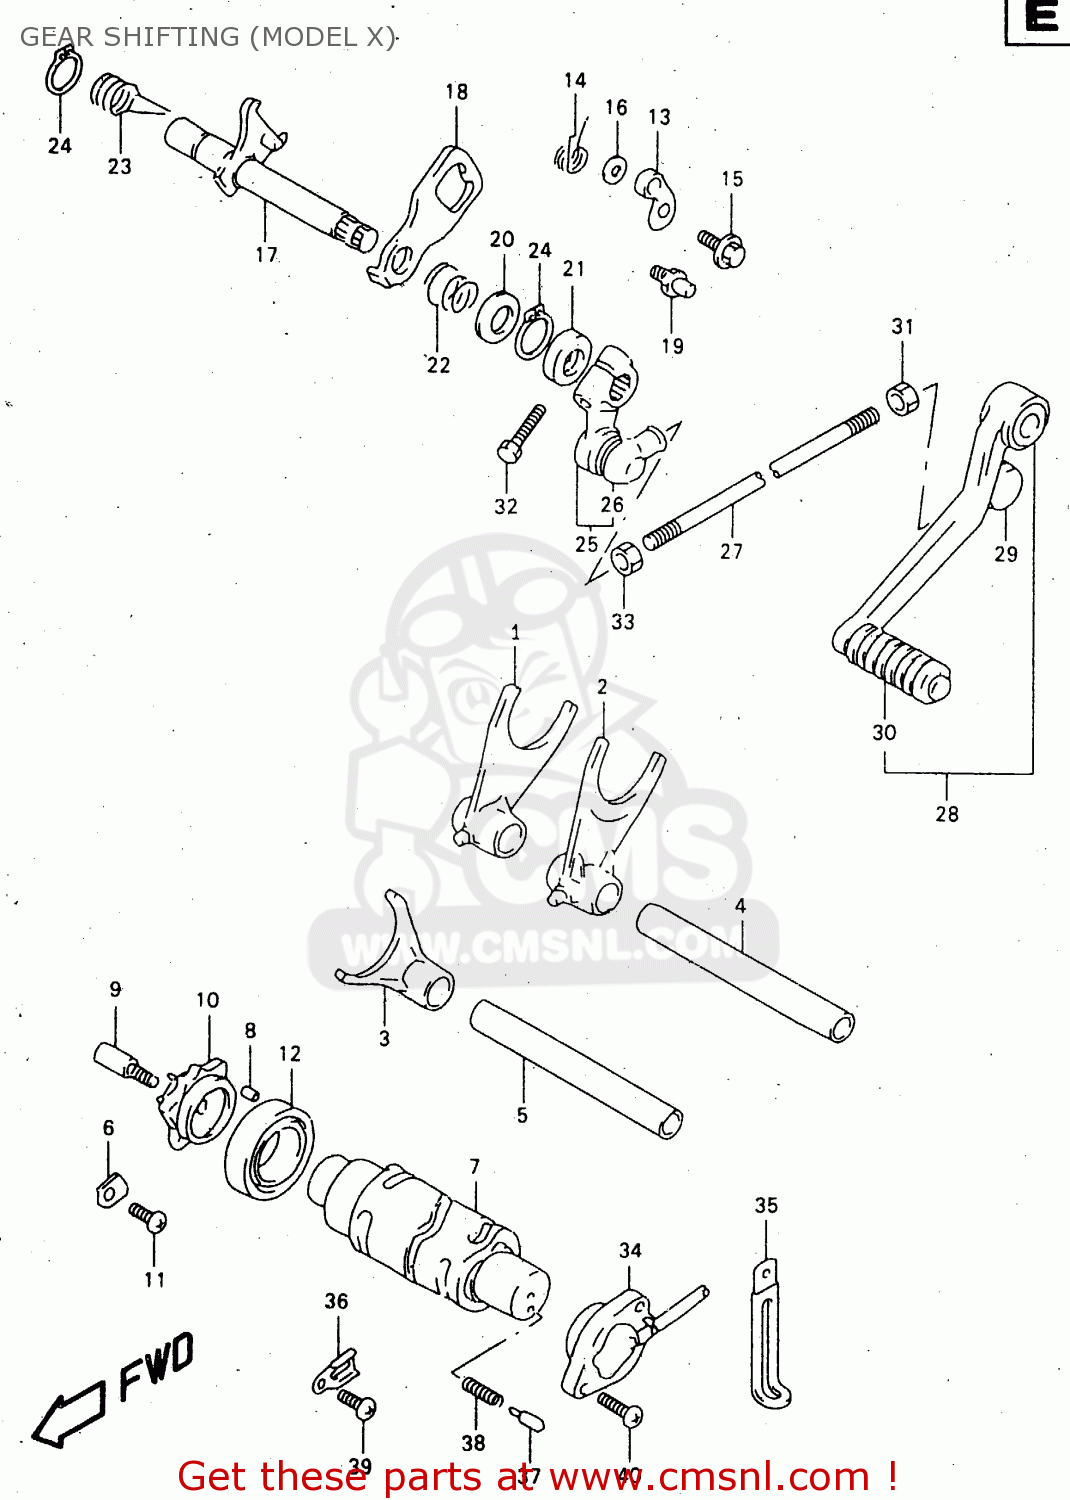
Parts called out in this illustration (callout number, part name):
1	FORK,GEAR SHIFT
2	FORK,GEAR SHIFT NO.1
3	FORK,GEAR SHIFT NO.3
4	SHAFT,GEAR SHIFT FORK
5	SHAFT,GEAR SHIFT FORK NO.2
6	RETAINER
7	CAM,GEAR SHIFT
8	PIN
9	PIN,SHIFT CAM DRIVEN GEAR
10	PLATE,GEAR SHIFT CAM
11	SCREW
12	BEARING
13	STOPPER,GEAR SHIFT CAM
14	SPRING,SHIFT CAM STOPPER
15	BOLT(6X14.3)
16	WASHER
17	SHAFT,GEAR SHIFT
18	PLATE,GEAR SHIFT CAM DRIVE
19	STOPPER,GEAR SHIFT CAM
20	SHIM(14X22X1)
21	SEAL,OIL(14X22X6)
22	SPRING
23	SPRING
24	CIRCLIP
25	ARM,GEAR SHIFT LINK
26	COVER,DUST
27	ROD,GEAR SHIFT LINK
28	LEVER ASSY,GEAR SHIFT
29	COVER,DUST
30	RUBBER,GEAR SHIFT PEDAL
31	NUT
32	BOLT
33	NUT
34	BASE ASSY,GEAR SHIFT TERMINAL
35	CLAMP(L:65)
36	CLAMP,GENERATOR LEAD WIRE
37	PIN(5X15.5)
38	SPRING
39	SCREW
40	SCREW
